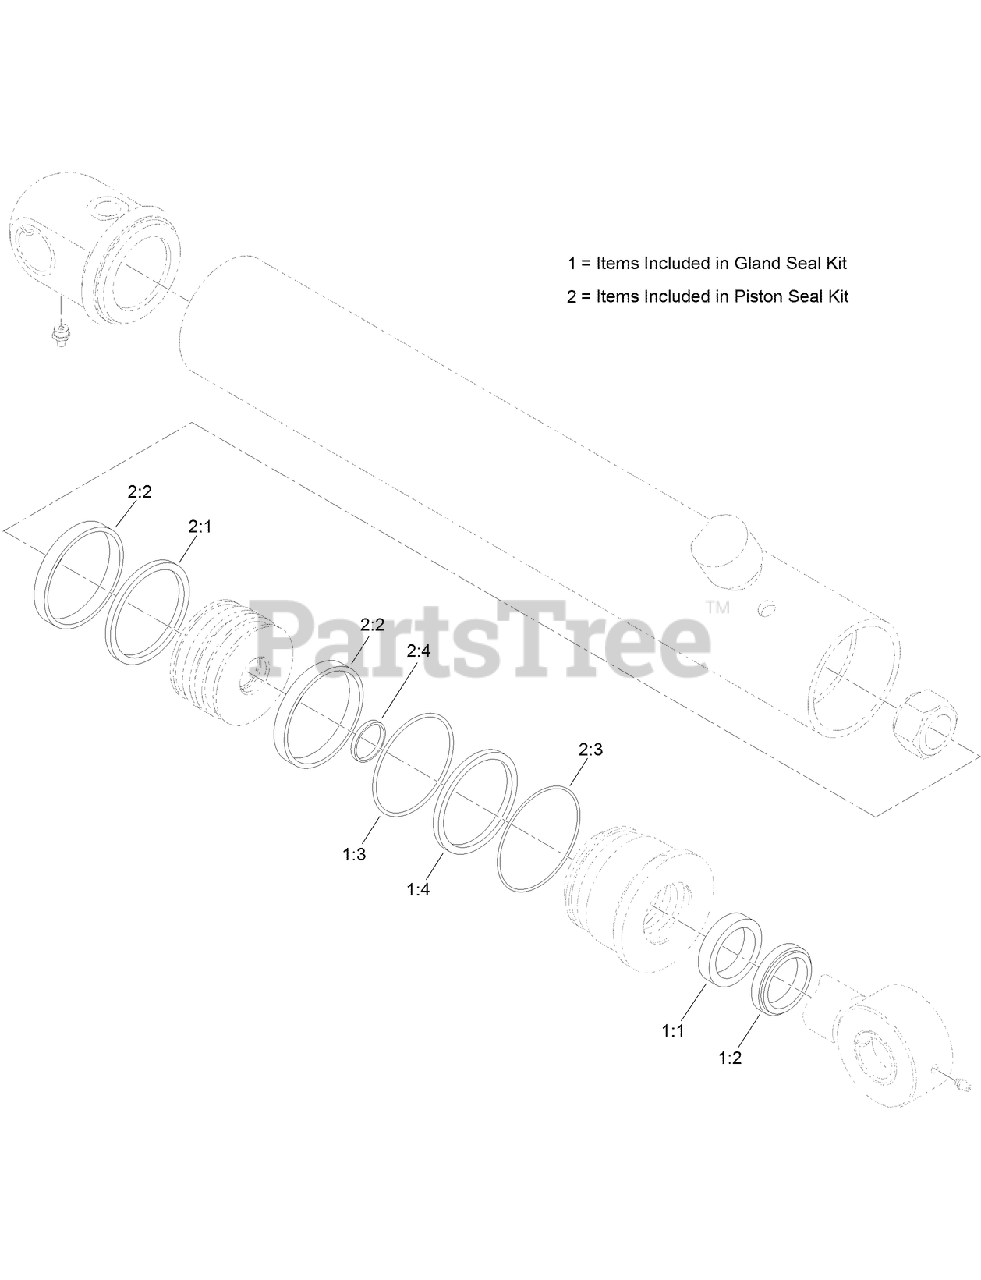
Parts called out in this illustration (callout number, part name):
1	GLAND SEAL KIT
1:1	SEAL-ROD
1:2	SEAL-WIPER
1:3	O-RING
1:4	RING-BACKUP
2	PISTON SEAL KIT
2:1	Seal-Piston
2:2	RING-WEAR
2:3	O-RING
2:4	O-RING
